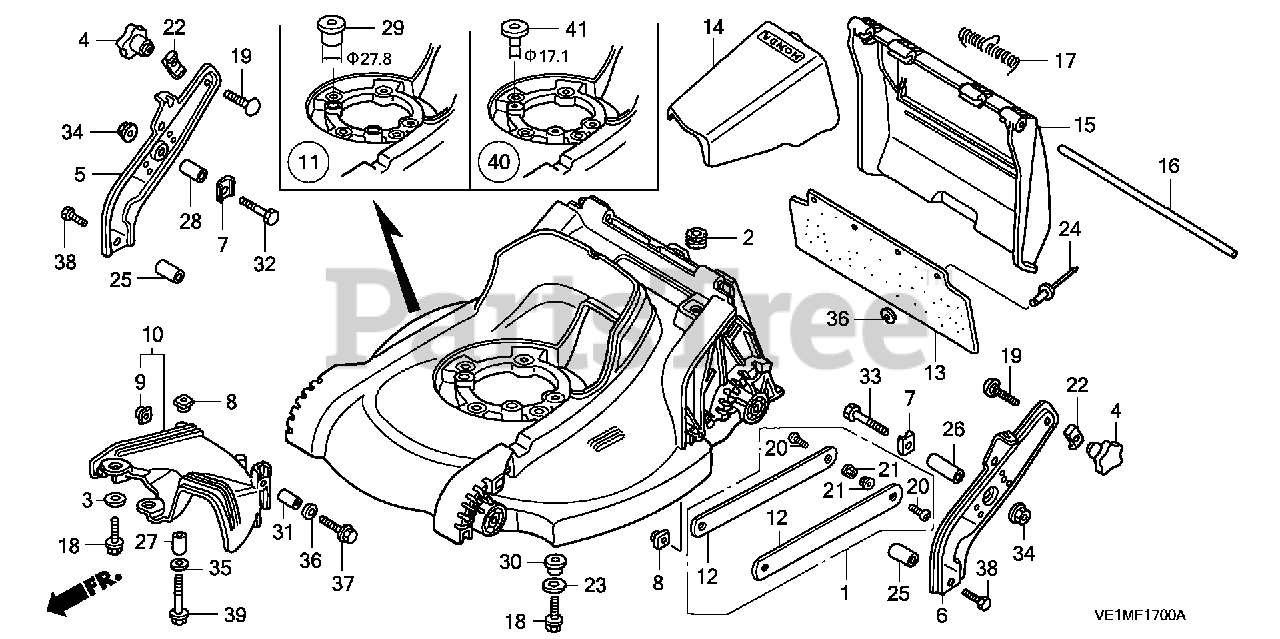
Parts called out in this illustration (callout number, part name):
1	GUARD KIT, HOUSING
2	RUBBER, BATTERY BOX MOUNTING
3	PLATE, HANDLE SETTING
4	GRIP, HANDLE JOINT (UPPER)
5	STAY, R. HANDLE *NH105* (MAT BLACK)
6	STAY, L. HANDLE *NH105* (MAT BLACK)
7	HOLDER, HANDLE STAY
8	NUT, HEADLIGHT SETTING
9	NUT, SPECIAL (6X7)
10	GUIDE ASSY., SCROLL *NH105Z* (MAT BLACK)
11	HOUSING *NH462* (VINTAGE GRAY SOLID)
12	GUARD, HOUSING
13	SHIELD, RR.
14	STUFFING *NH105* (MAT BLACK)
15	GUARD, DISCHARGE
16	SHAFT, DISCHARGE GUARD
17	SPRING, GUARD RETURN
18	BOLT, ENGINE SETTING
19	BOLT, PAN (8X35)
20	SCREW, HOUSING GUARD
21	NUT, FLANGE
22	WASHER, FRAME JOINT
23	WASHER, ENGINE MOUNTING
24	RIVET (6MM)
25	COLLAR, STAY (LOWER)
26	COLLAR, L. STAY (UPPER)
27	COLLAR, HANDLE
28	COLLAR, R. STAY (UPPER)
29	COLLAR A, BED
30	COLLAR B, BED
31	COLLAR, SCROLL
32	BOLT, HEX. (8X40)
33	BOLT, HEX. (8X55)
34	NUT, FLANGE (8MM)
35	WASHER, PLAIN (8MM)
36	WASHER, PLAIN (6MM)
37	BOLT, FLANGE (6X35)
38	BOLT, FLANGE (8X22)
39	BOLT, FLANGE (8X45)
40	HOUSING, CUTTER *NH462* (VINTAGE GRAY SOLID)
41	COLLAR C, BED
